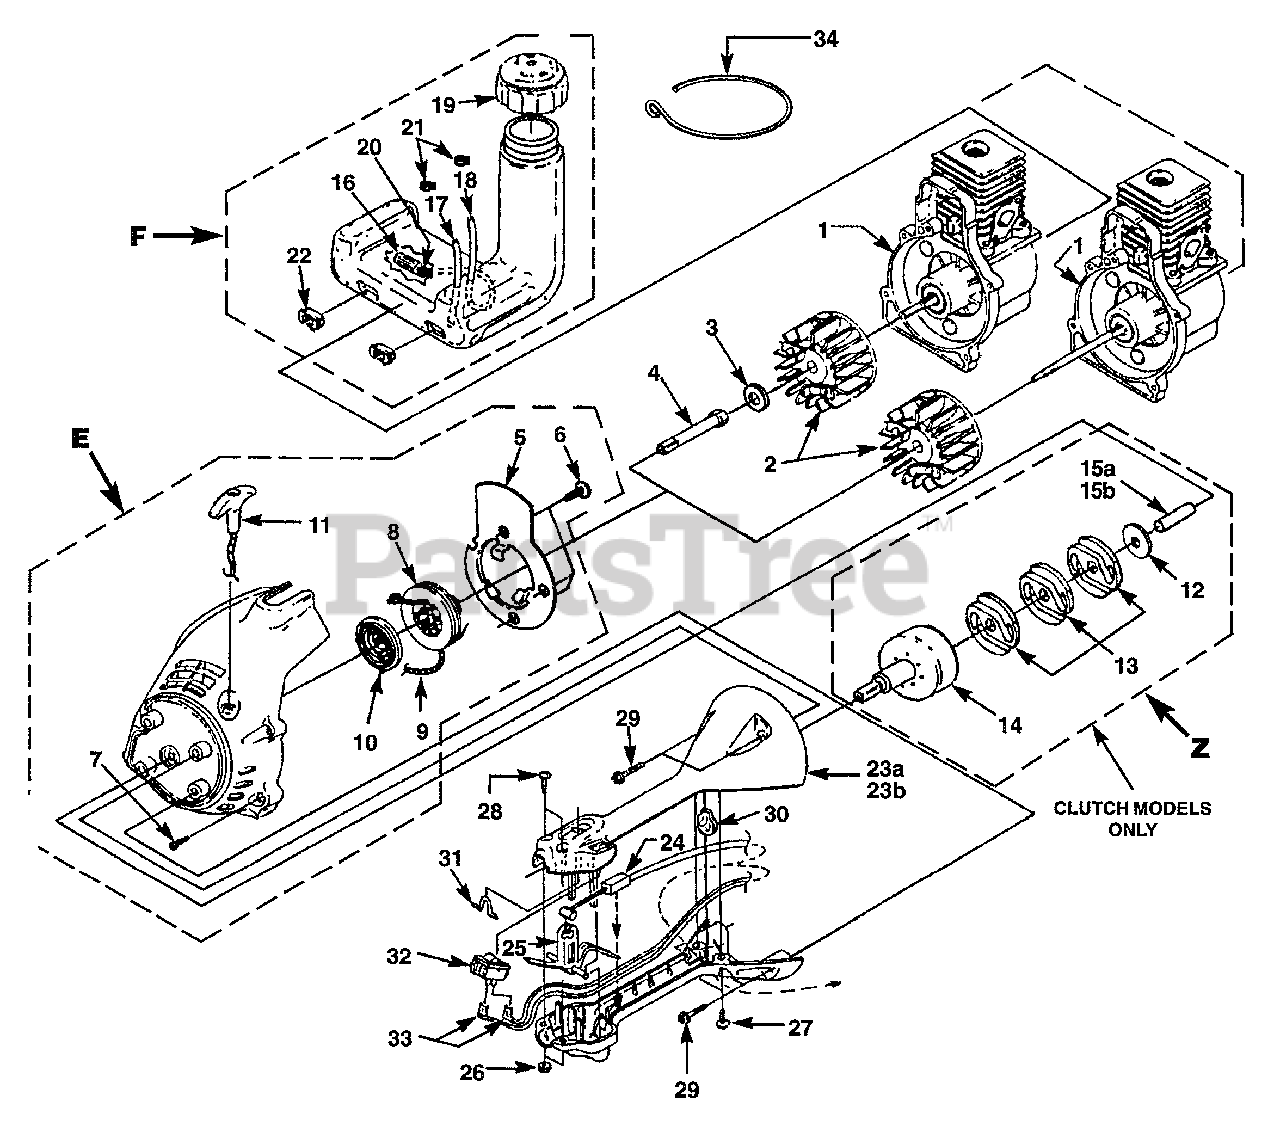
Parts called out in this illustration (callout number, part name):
1	SHORT BLOCK
2	ROTOR w/Starter Pawls
3	WASHER-Flat (5/16)
4	CONNECTOR-Drive
5	PLATE-Baffle
6	SCREW-Plastite (8-16 X 5/8")
7	SCREW-Thread Form. (10-24 X 3/4")
8	PULLEY-Starter
9	ROPE-Starter (42")
10	SPRING & CONTAINER
11	GRIP-Starter
12	WASHER-Flat
14	CONNECTOR & DRUM
15A	SPACER (30CC) 3 Shoe Clutch
15B	SPACER (25CC) 2 Shoe Clutch
16	FILTER-Fuel
17	TUBING-Rubber (5 1/2")
18	TUBING-Rubber (7")
19	FUEL CAP
20	CLAMP
22	BUMPER-Rubber
23A	CONTROL HANDLE (W/O Switch)
23B	CONTROL HANDLE
24	CABLE-Throttle
25	TRIGGER
26	NUT-Hex (#10-24)
27	SCREW-Plastite (#10-14 X 7/8")
28	SCREW-Machine (#10-24 X 1 1/4")
29	SCREW-Plastite (#10-14 X 1 1/8")
30	STOP-Drive Shaft
31	HOOK-Strap
32	SWITCH-Rocker
33	LEADS-Electrical
34	SUPPORT-Wire
E	COMPLETE STARTER ASSEMBLY
Z	CLUTCH & DRUM Kit
F	FUEL TANK COMPLETE
